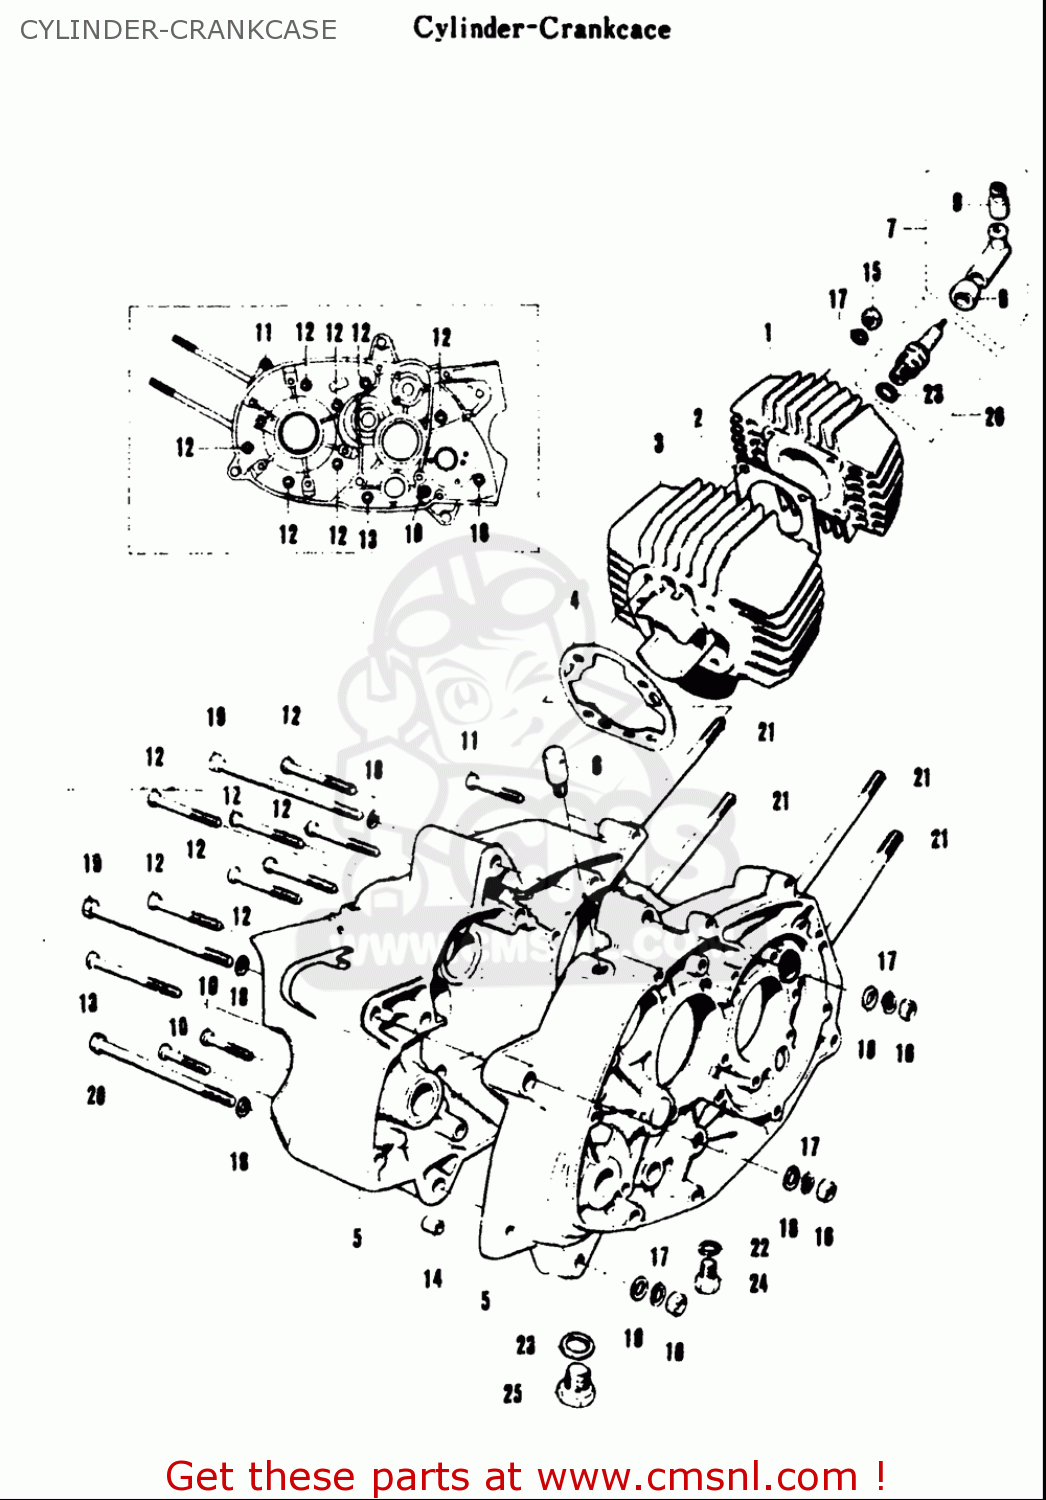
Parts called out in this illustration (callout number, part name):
2	GASKET,CYLINDER HEAD (NAS)
4	GASKET,CYLINDER
6	PLUG,T/M BREATHER
10	SCREW
11	SCREW
12	SCREW
13	SCREW
14	PIN
15	NUT
16	NUT
17	WASHER,LOCK
18	WASHER
19	BOLT(8X105)
21	BOLT,STUD
22	GASKET(10X14X3.6) (NAS)
23	GASKET(14X19.2X2) (NAS)
24	PLUG
25	PLUG(MAGNETO)
